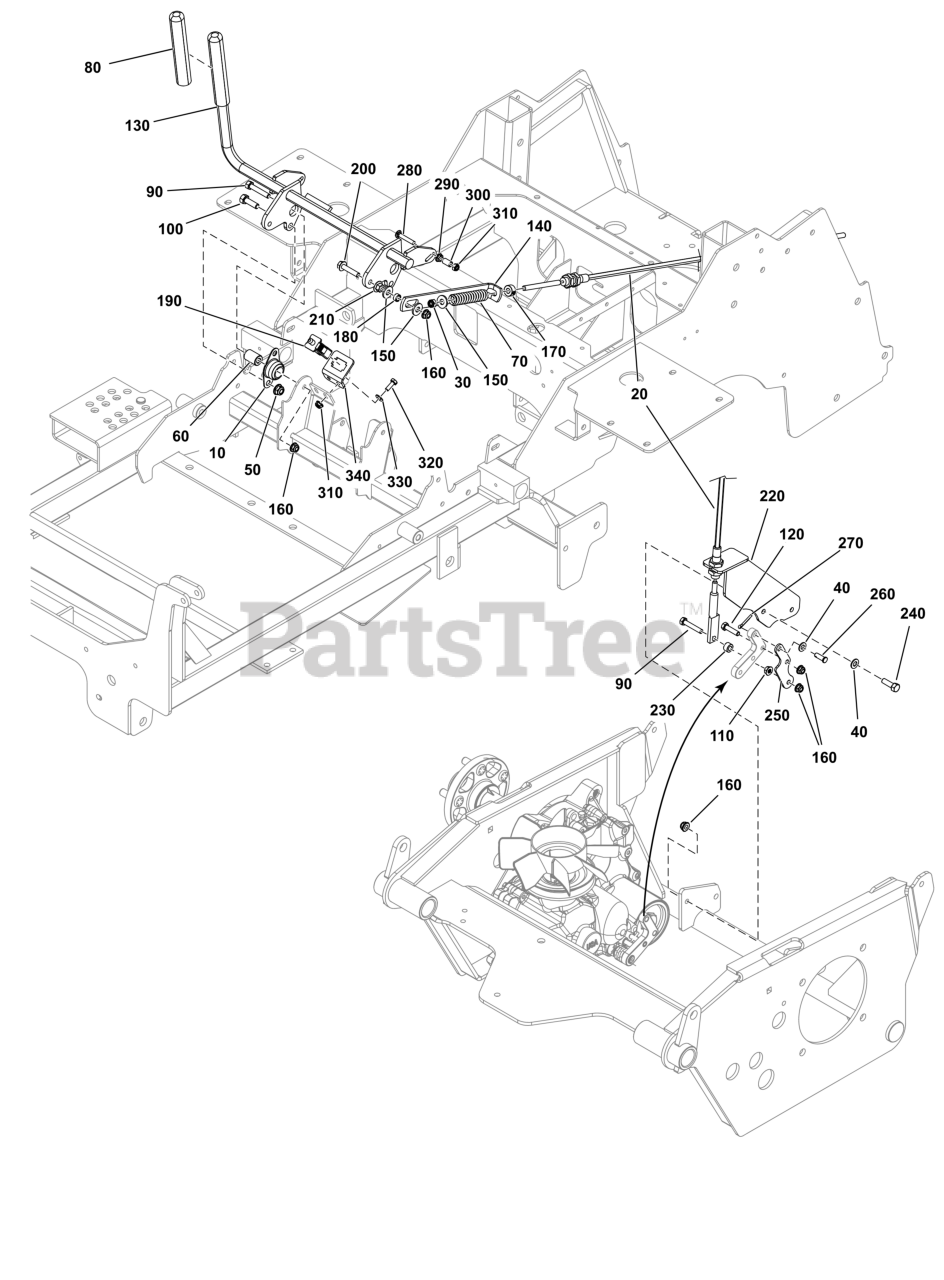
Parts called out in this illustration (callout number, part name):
10	BEARING, BRONZE FLANG
20	CABLE, PARKING BRAKE
30	NUT, 5/16-24 HEX NYLO
40	WASHER
50	NUT, 3/8-16 HEX NYLOCK
60	SPACER, .32 X .75 X 1
70	SPRING, COMP. 1/2 ID
80	GRIP, FOAM
90	BOLT, 5/16-18 X 1-3/4
100	BOLT, 3/8-16 X 3/4" G
110	NUT, 5/16-18 HEX SERR
120	BOLT, 5/16-18 X 1-1/4
130	WELD, BRAKE SHAFT, LOCKOUT, P1/P2 (w/ Grip)
140	ARM, Link
160	NUT
170	COLLAR, 5/16" SET
180	SPACER, .33 X .50X.25
190	SWITCH, DP NO/NC SNAP
200	BOLT - 5/16-18
210	NUT, 5/16-18 HEX SERR
220	BRACKET, Brake
230	SPACER, .33X.625X.360
250	PLATE, BRAKE ARM
260	PIN, CLEVIS
270	PIN - COTTER
280	BOLT, 1/4-20 X 1.5
310	NUT, 1/4-20 HEX NYLON
320	BOLT, 1/4-20 X 3/4" G
330	WASHER
